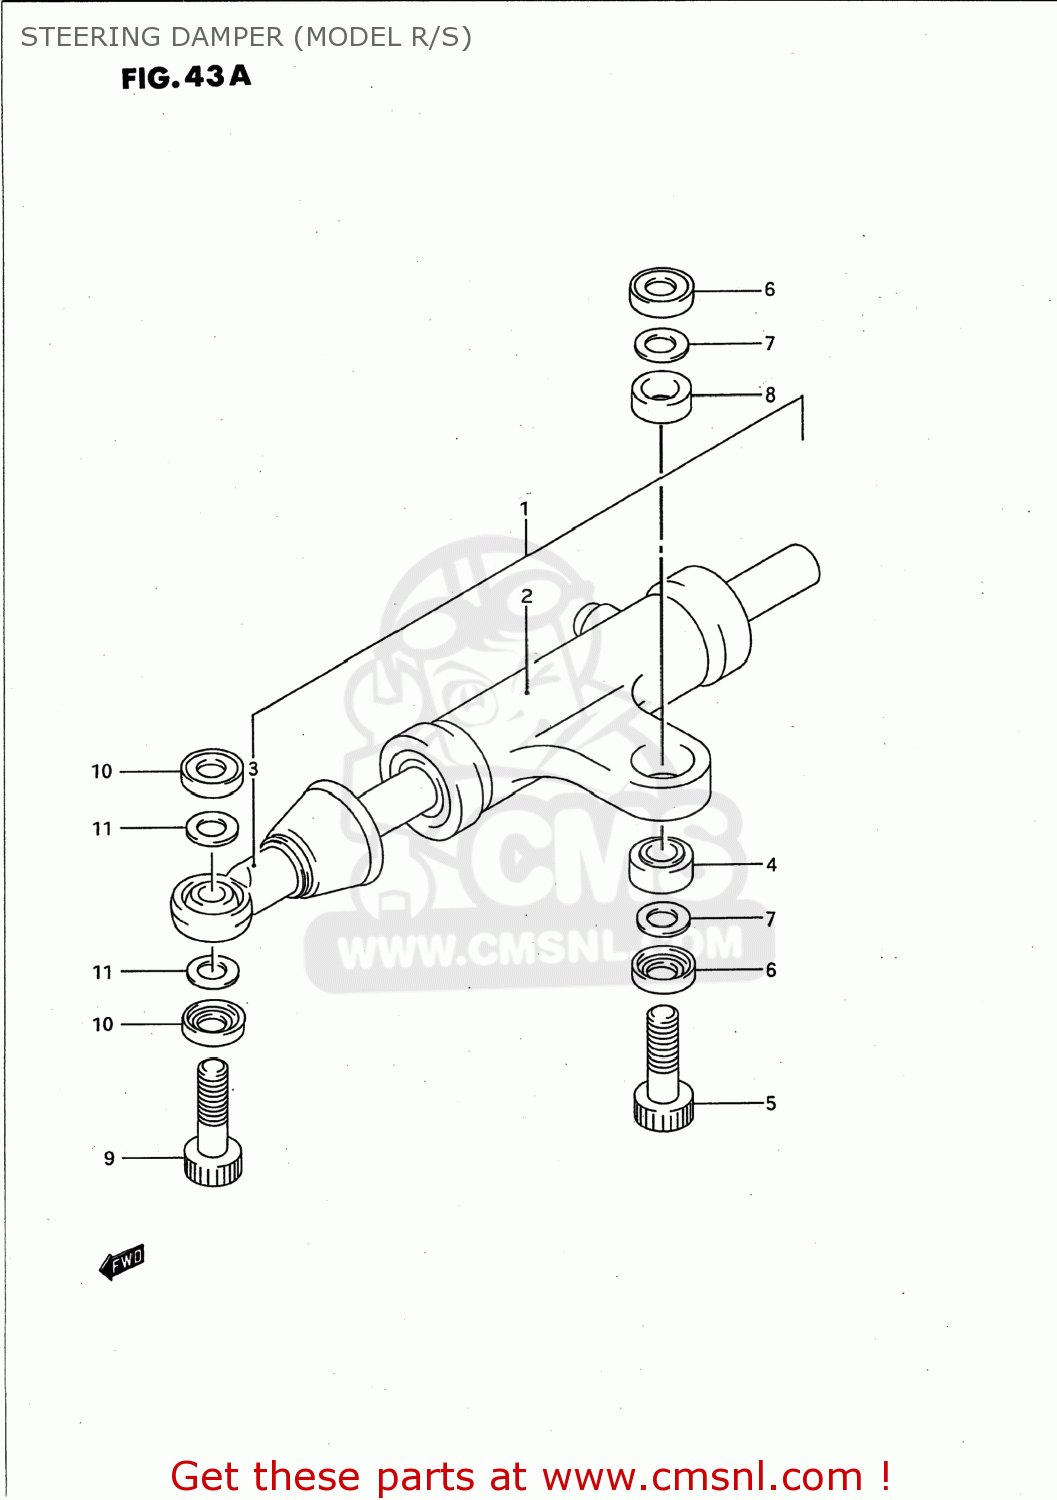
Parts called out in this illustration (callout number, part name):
1	DAMPER ASSY,STEERING
2	DAMPER,STEERING
3	PILLOW BALL,ROD END
4	BEARING(8X17.5X11)
5	BOLT
6	7
7	SHIM
8	SPACER (8.4X14X6)
9	BOLT
10	11
11	SHIM
